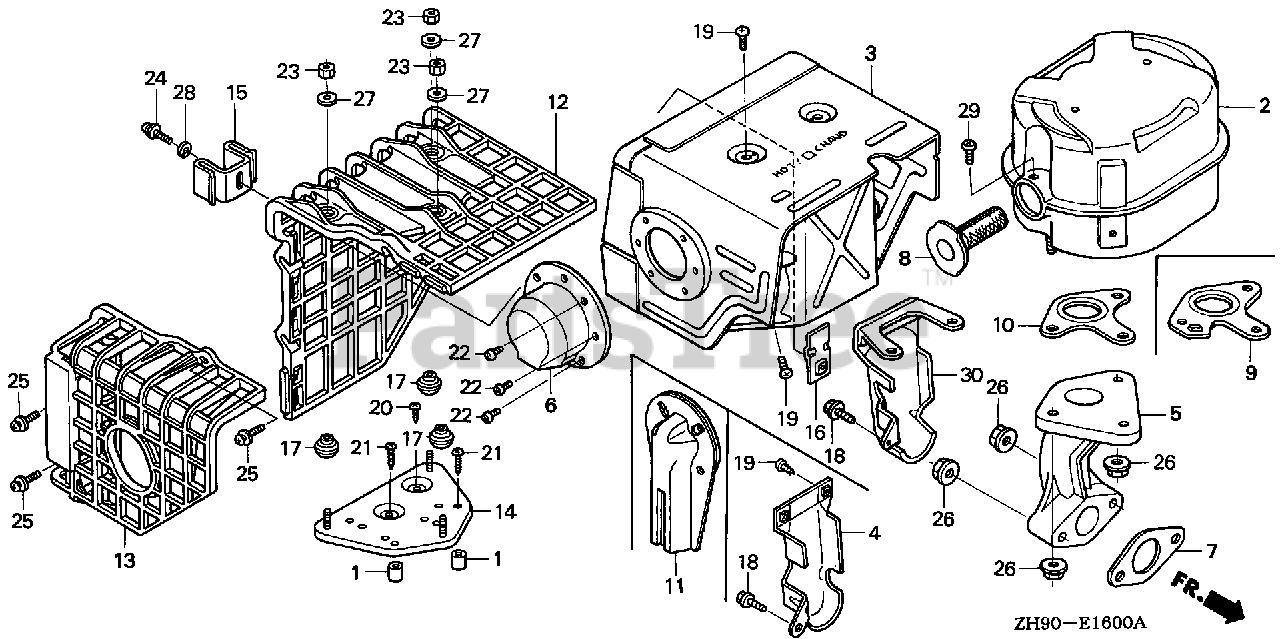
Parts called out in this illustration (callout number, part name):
2	MUFFLER
3	PROTECTOR, MUFFLER (STD)
4	PROTECTOR, EX. PIPE
6	CAP, MUFFLER
7	GASKET, EX. PIPE
8	ARRESTER, SPARK
9	GASKET, MUFFLER (ARRESTER) (NIPPON LEAKLESS)
10	GASKET, MUFFLER (NIPPON LEAKLESS)
18	BOLT, FLANGE (6X12) (CT200)
19	SCREW, TAPPING (5X8)
22	SCREW, TAPPING (4X6)
26	NUT, FLANGE (8MM)
29	SCREW, TAPPING (5X8)
